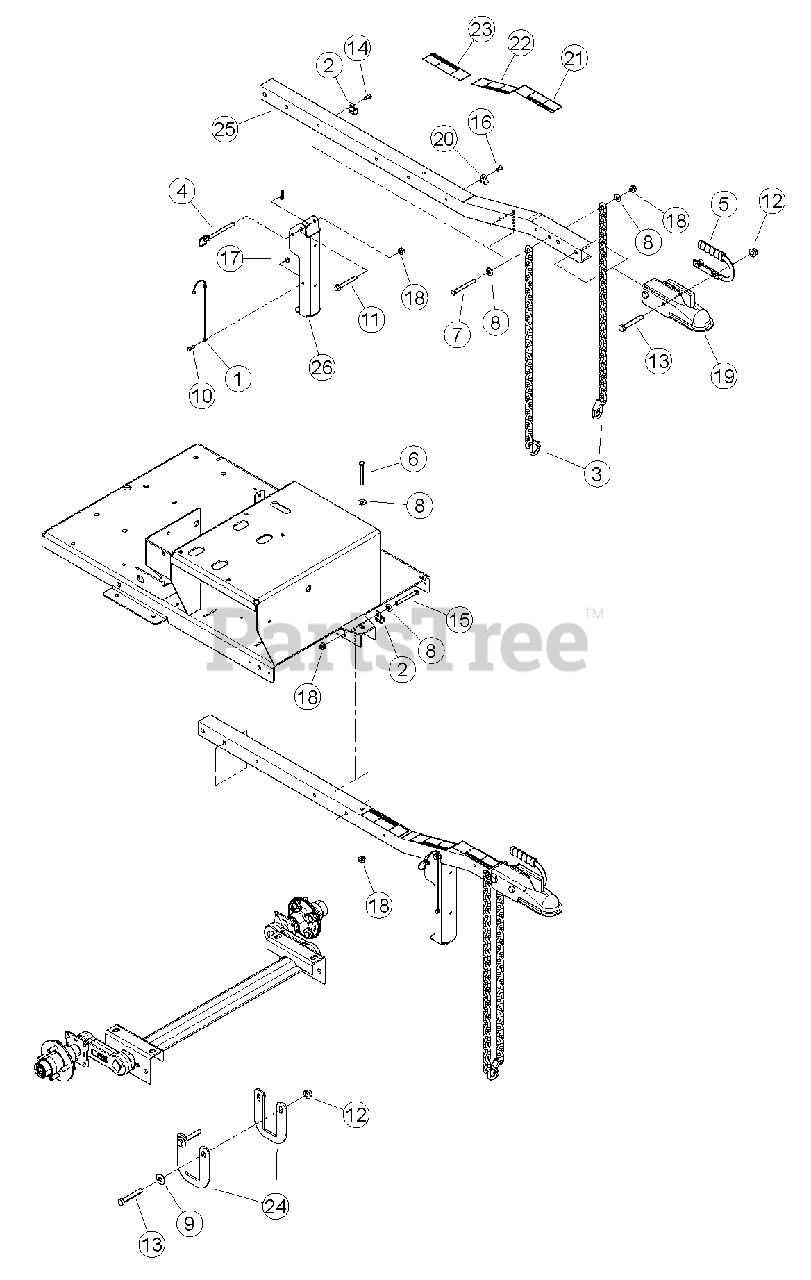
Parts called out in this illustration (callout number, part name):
1	LANYARD, NYLON
2	CLAMP, 9/16 COATED
3	CHAIN, SAFETY 5000 LB W/ LATCH
4	PIN, 3/8 HITCH
5	HANDLE, HITCH COUPLER
6	BOLT, 3/8-16 X 3 GR5 HEX CAPSCREW
7	BOLT, 3/8 X 3-1/2" HEX HD GR5 ZP
8	WASHER, 3/8 FLAT
9	WASHER, 1/2 FLAT
10	BOLT, 1/4-20 X 3/4 HWH GR5 CZP
11	BOLT, 3/8 X 3 FLANGE NC
12	NUT, 1/2-13 NYLOCK FLANGE
13	BOLT, 1/2 X 3-1/4 HCS GR5 ZP
14	SCREW, 11/32-12 X 7/8 HWH T-AB
15	BOLT, 3/8 X 3-1/4 HEX HD GR5 ZP
16	RIVET, AL BLIND 1/4 X 3/4 DOME HEAD
17	NUT, 1/4-20 NYLOCK FLANGE
18	NUT, 3/8-16 NYLOCK FLANGE
19	COUPLER, TRAILER HITCH
20	CLAMP, CABLE MOUNT
21	DECAL, SAFETY CHAINS
22	DECAL, TRAILER ELECTRICAL
23	DECAL, SAFE COUPLING
24	PLATE, HITCH SADDLE
25	POLE, C/S HITCH
26	WELDMENT, STAND JACK
